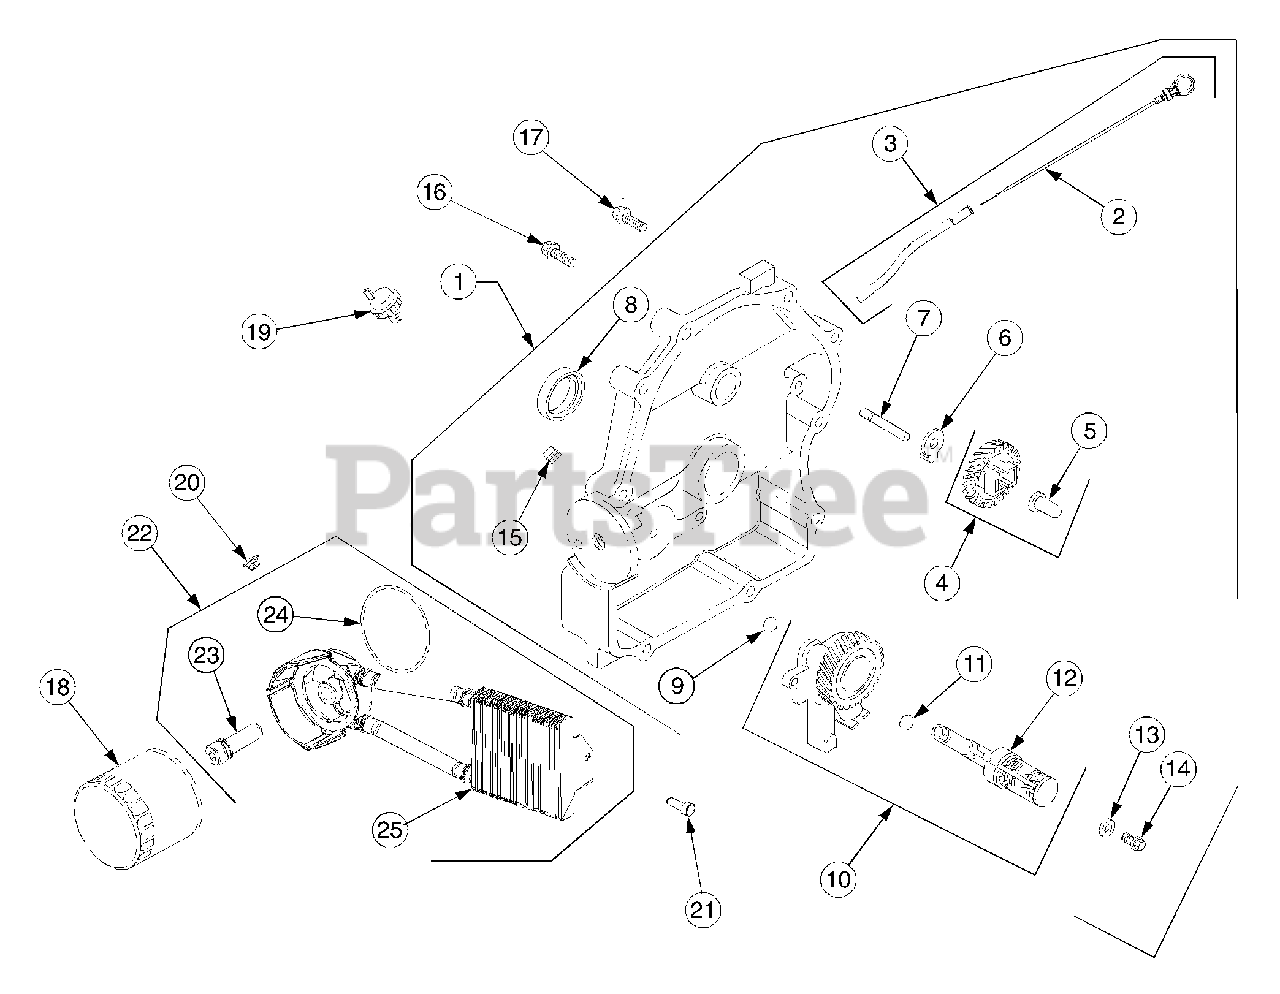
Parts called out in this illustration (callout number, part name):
1	Plate Assy, Closure
3	Tube, Dipstick
4	Kit, Governor Gear
5	Pin, Governor Regulating
7	Shaft, Governor Gear
8	Seal, Oil (PTO end)
10	Oil Pump Assy
11	O-Ring, Oil Pick-up
12	Pick-up, Oil
13	Washer, Plain
14	Screw, Hex Flange, M6 x 1.0 x 25
15	Plug, Pipe 1/8
16	Screw, Hex Flange, M8 x 1.25 x 45
17	Screw, Hex Flange, M8 x 1.25 x 45
18	Filter, Oil
19	Switch, Pressure
20	Nut, Plastic
22	Kit, Oil Cooler
23	Nipple, Oil Filter
